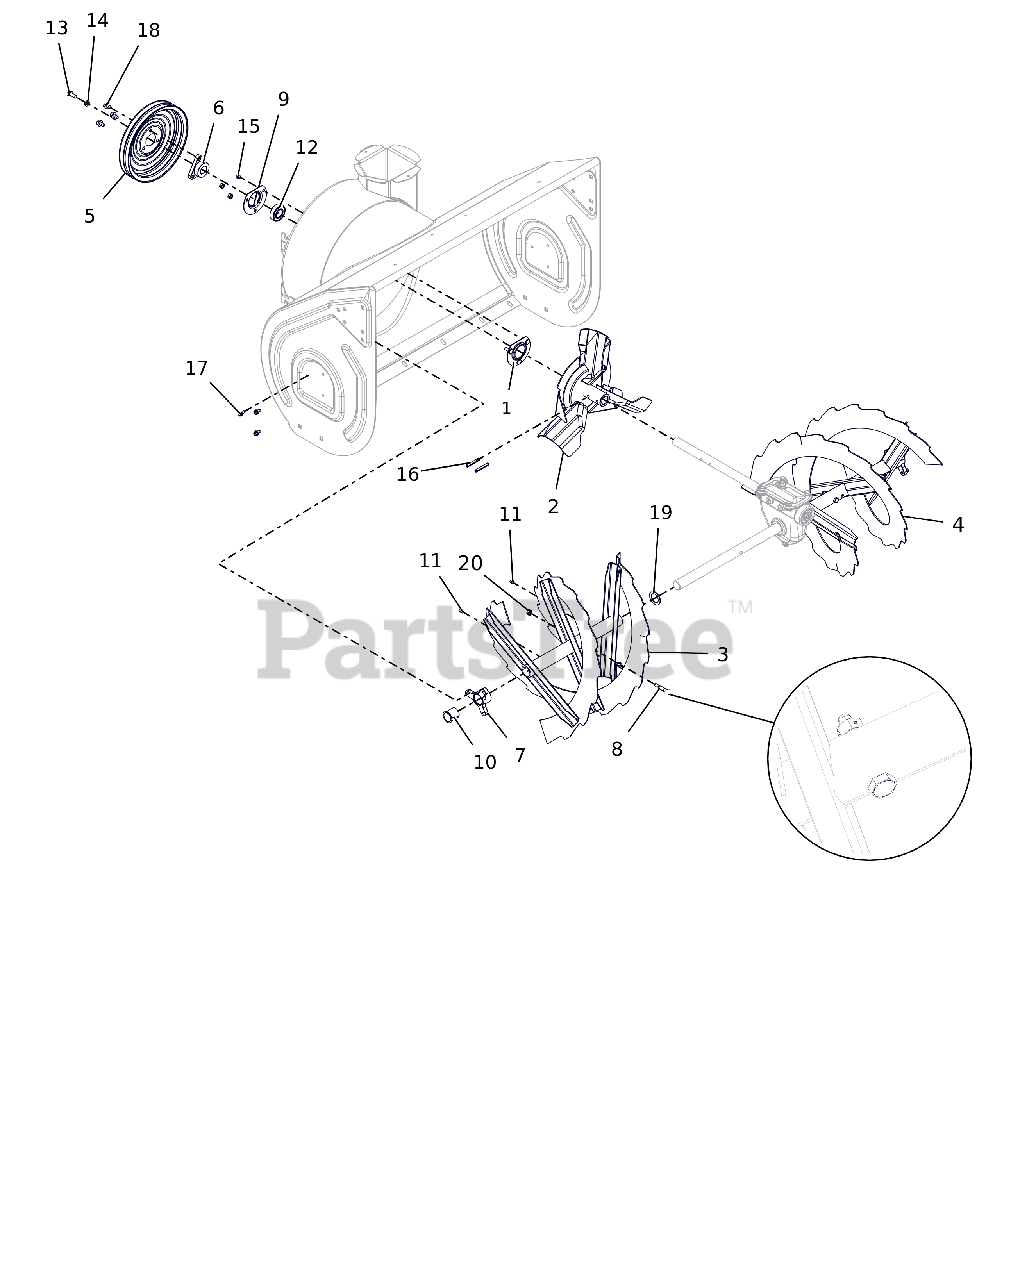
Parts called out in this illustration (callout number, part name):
1	BEARING FLANGE
2	IMPELLER, 3 BLADE-14"
3	RAKE, RH-32"(1 ID X 15.75 OD)
4	RAKE, LH-32"(1 ID X 15.75 OD)
5	PULLEY, SPIN FORM DUAL GROOVE
6	PULLEY HUB, D-BORE .87 PRO
7	BUSHING, RAKE SHAFT 1"
8	BOLT, SHEAR - DELUXE
9	BEARING FLANGE
10	BSHG-FLG SPLIT NYLINER 1.0" HP
11	ZERK,FITTING .25X.125 DRIVE IN
12	BRG-BALL .876X1.75X.50 RSTFP
13	BLT-HEX .31-24X.75 YWZC GR5
14	WSHR-LK .312X.097 HVY YWZC
15	@NUT-LK-CTR .25-20 YWZC
16	PIN-ROLL .250X1.75
17	SCR-TAP .25-20X.50 HWH TR YWZ
18	@SCR-TAP .31-18X.50 HWH TR YWZ
19	WSHR-FL-STL 1.010X1.505X.062YZ
20	@NUT-LK-CTR .31-18 YWZC
